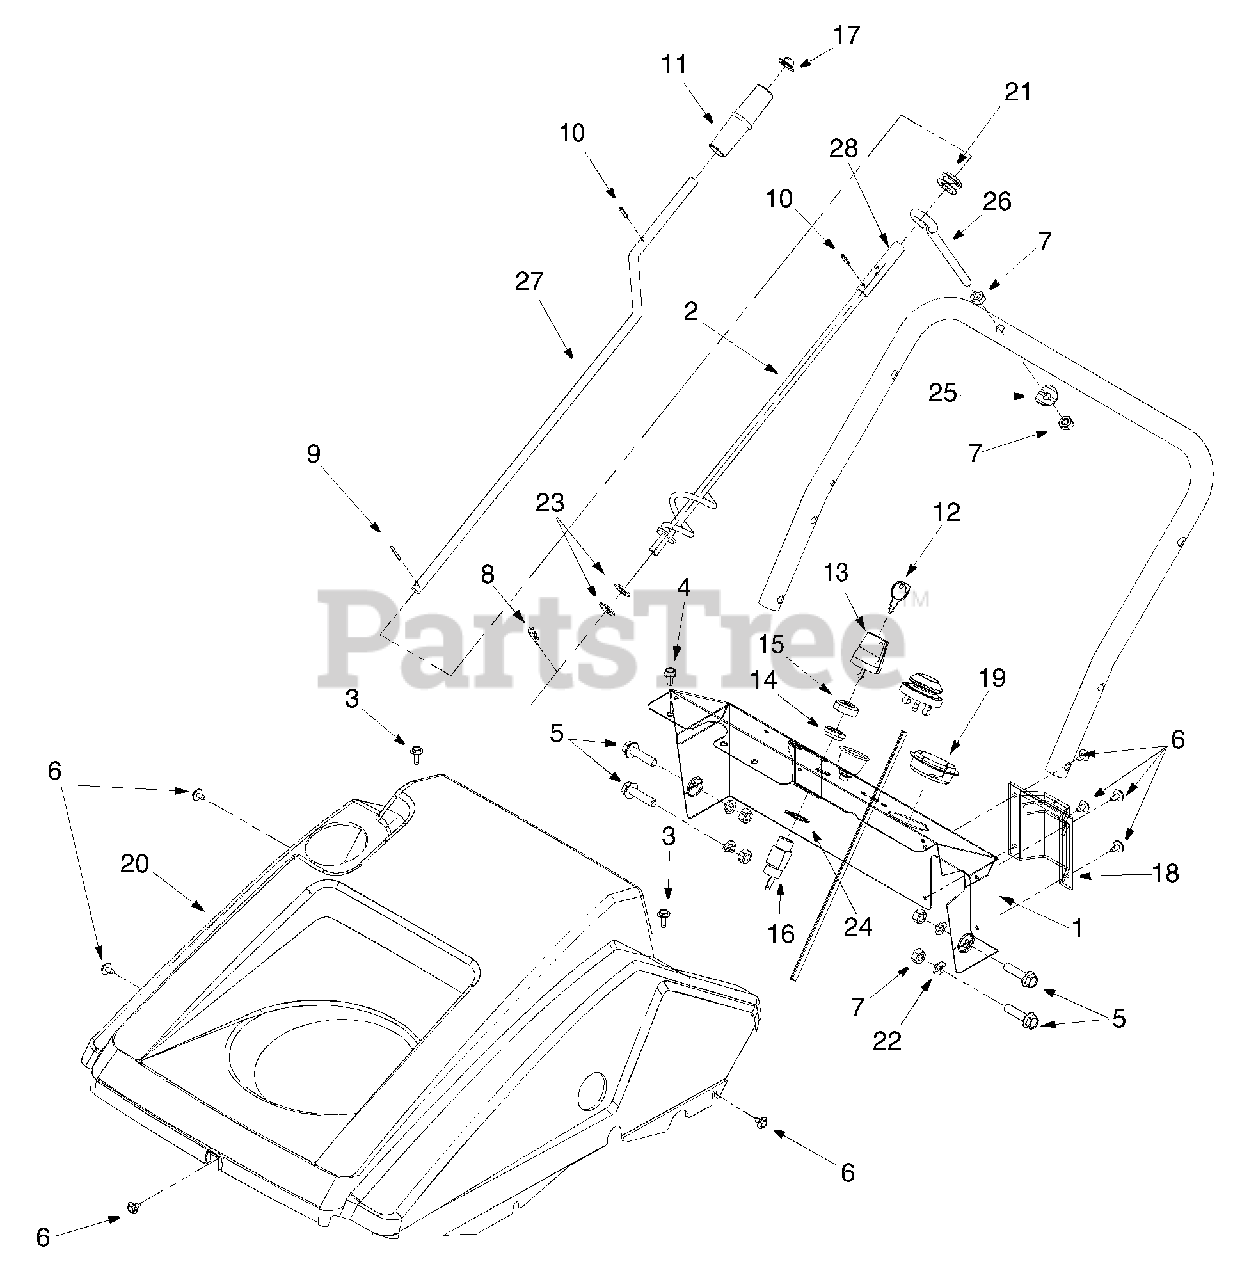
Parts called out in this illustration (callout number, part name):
4	Screw-Hex
6	Screw-Hex
8	Cotter Pin
9	Cotter Pin
10	Pin Roll
11	Knob-Chute Crank
12	Key-Ignition Switch
13	Key-Ignition-Std
14	Ignition Switch Nut
15	Ignition Switch Cap
16	Ignition Switch
18	Cover-Choke
19	Plug
22	Washer-Lock
23	Washer-Flat
24	Washer Internal Lock
26	Eyebolt Chute Crank
28	Spacer
